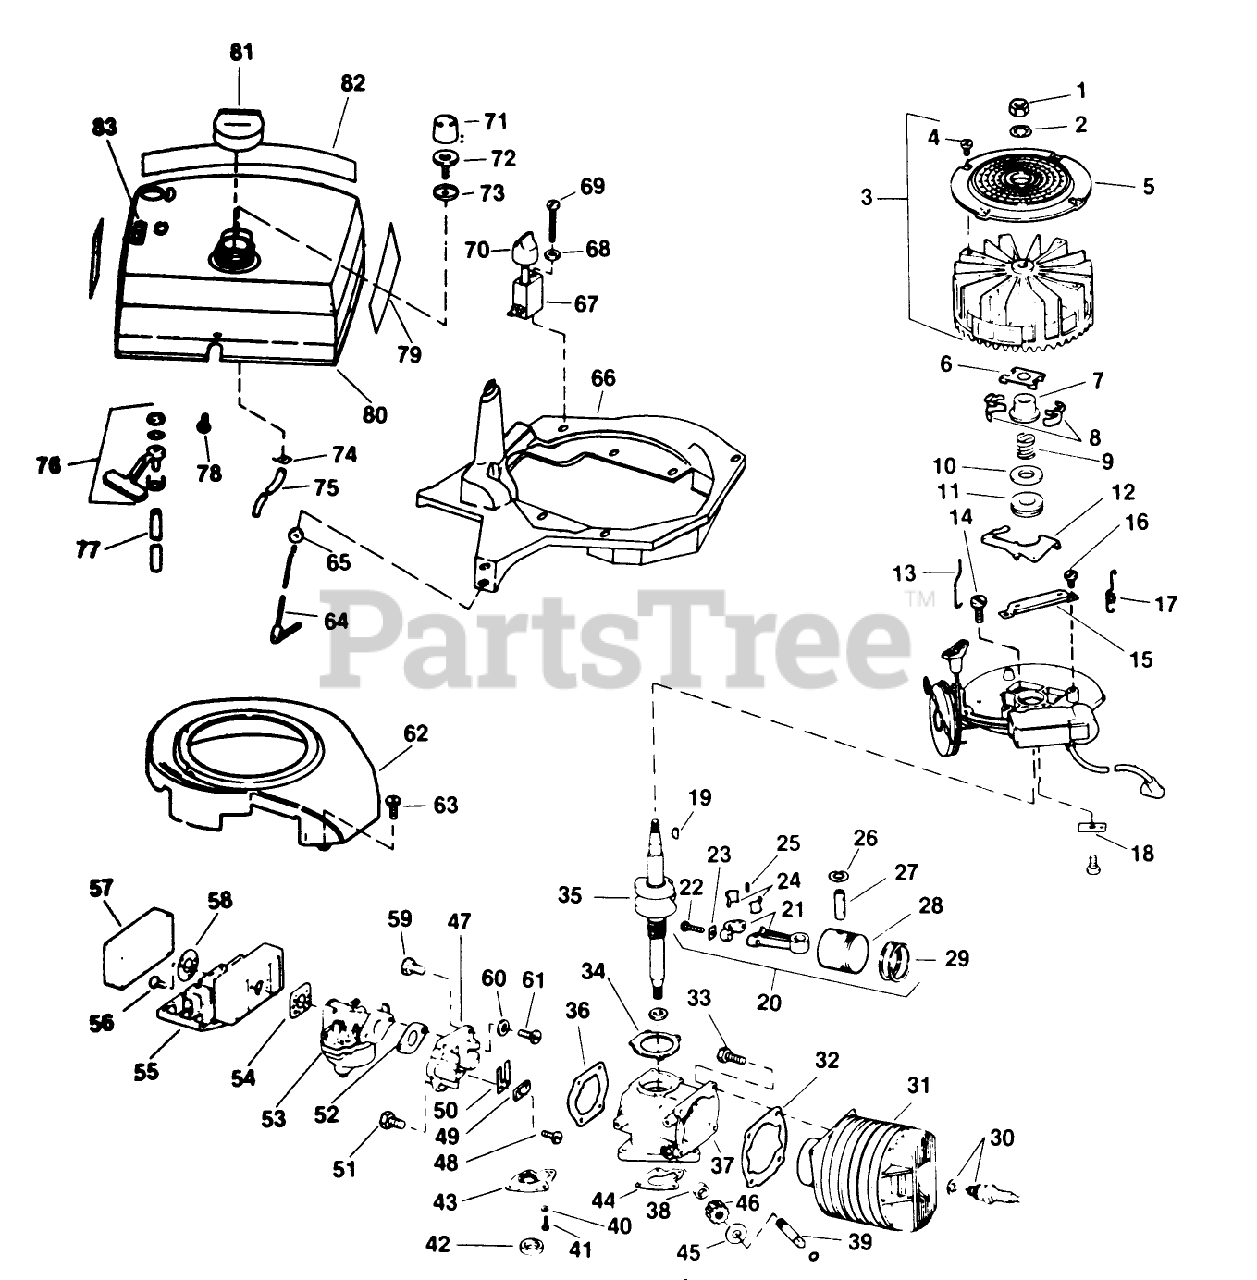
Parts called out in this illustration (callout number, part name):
1	NUT
4	SCREW F
6	YOKE S
7	COLLAR S
9	SPRING S
12	LEVER-GOVERNOR S
13	ROD
14	SCREW S
15	BRACKET
16	SCREW S
17	SPRING
18	Tab
19	KEY
22	SCREW
24	LINER ASM
26	RING-RETAINING
30	Spark Plug
32	GASKET S
34	GASKET S
36	GASKET S
38	SEAL S
41	SCREW
43	GEAR COVER S
44	GASKET-CVR S
45	THRUST WASHER
46	GEAR, DR SHAFT S
47	REED PLATE AY. S
49	PLATE-BACKUP, REED
51	SCREW S
52	GASKET S
54	GASKET S
55	CASE
56	SCREW S
57	AIR FILTER S
58	WASHER S
59	SCREW S
62	BAFFLE
65	GROMMET
68	WASHER S
73	CUP-BULB
74	LOCKNUT S
78	SCREW S
